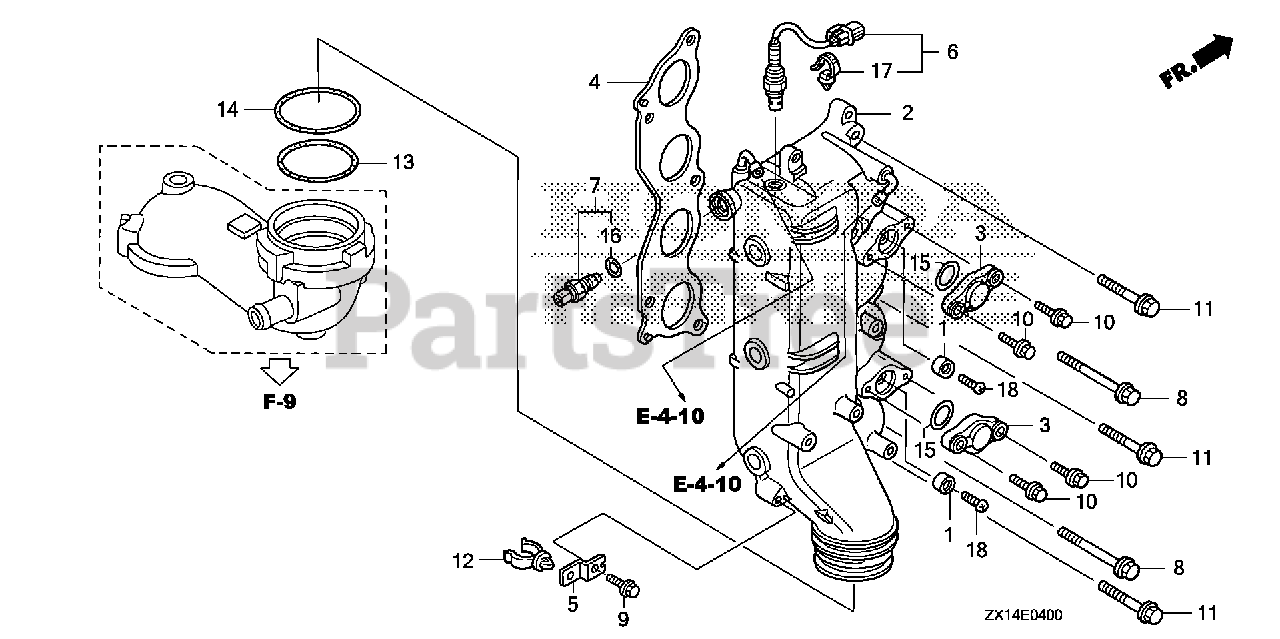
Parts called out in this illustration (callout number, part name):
1	METAL, ANODE
2	MANIFOLD, EX. *NH8* (DARK GRAY)
3	COVER, EX. MANIFOLD *NH8* (DARK GRAY)
4	GASKET, EX. MANIFOLD
5	BRACKET, WATER TUBE CLAMP
6	SENSOR, LAF
7	SENSOR ASSY., WATER TEMPERATURE
8	BOLT, FLANGE (10X75)
9	BOLT, FLANGE (6X14)
10	BOLT, FLANGE (6X22)
11	BOLT, FLANGE (10X45)
12	CLAMP B, WATER TUBE
13	O-RING (76.4X3.1)
14	O-RING (79.8X3.1)
15	O-RING (37X2.4)
16	O-RING (9.5X1.9)
17	CLIP, HARNESS BAND (145.2MM) (NATURAL)
18	SCREW, PAN (6X18)
